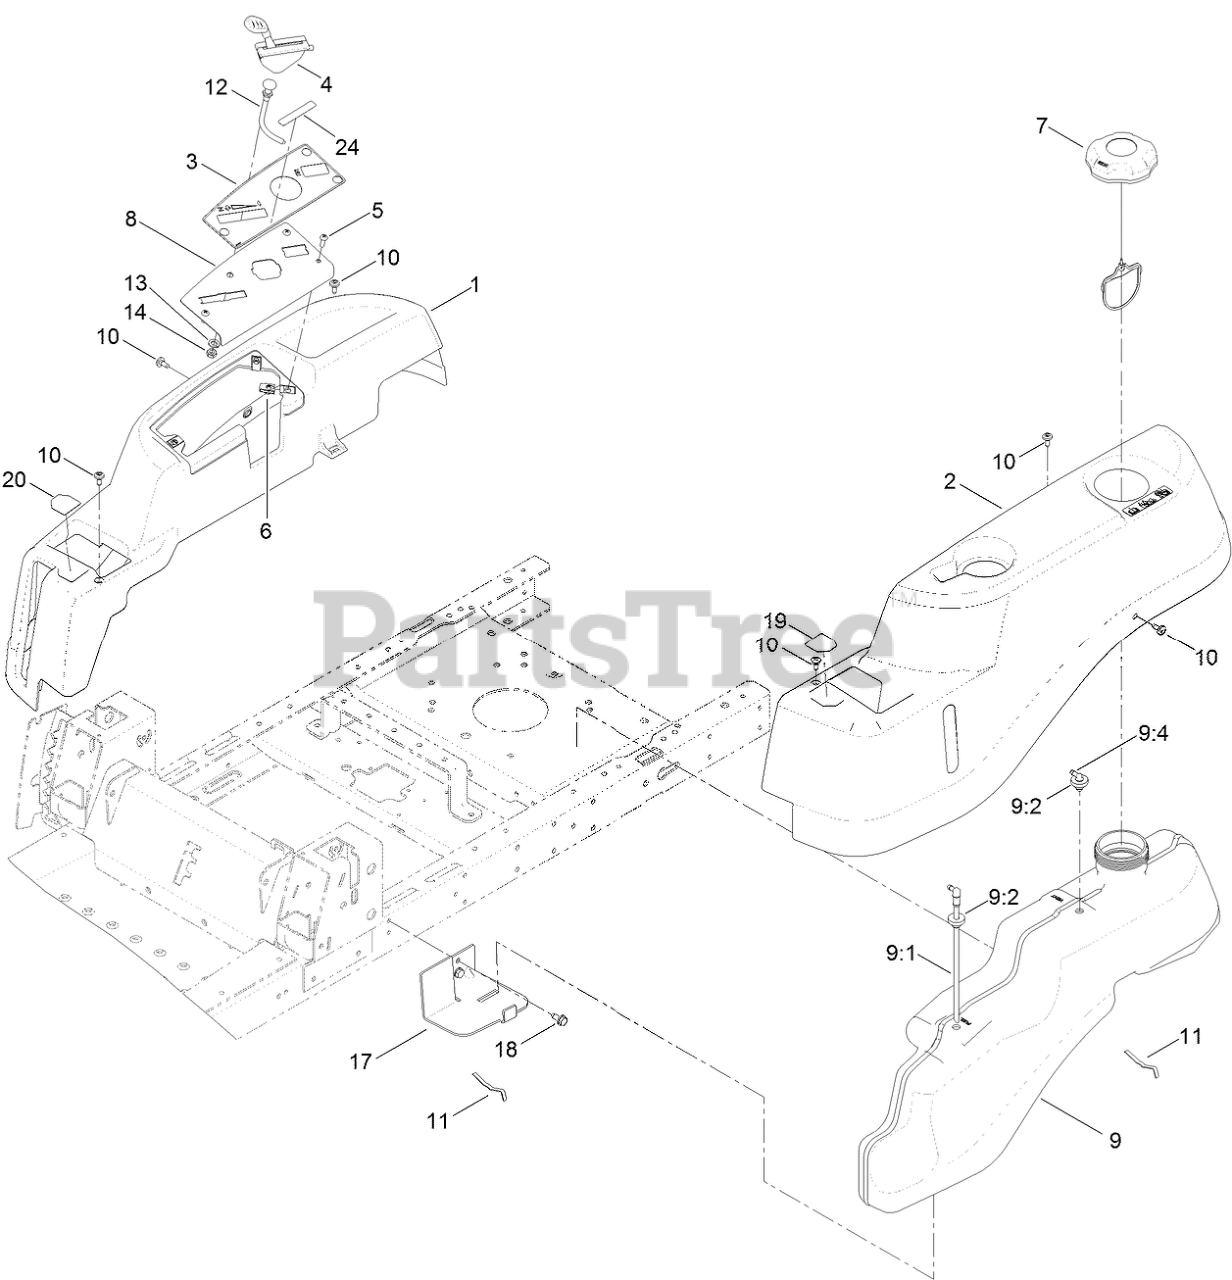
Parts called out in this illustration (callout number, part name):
1	POD-RH
2	POD-LH
3	DECAL-PANEL, CONTROL
4	CABLE-THROTTLE
5	SCREW-PRH
7	CAP-FUEL, RATCHETING
8	PLATE-CONTROL
9	FUEL TANK ASM
9:1	CONNECTOR-ELBOW, 90 DEG
9:2	BUSHING
9:4	FITTING-PLASTIC
10	SCREW-SHOULDER
11	SPRING
12	CABLE-CHOKE
13	WASHER-LOCK
14	NUT-HJ
17	SUPPORT-TANK, FRONT
18	SCREW-HWHTF
19	DECAL-CONTROL LEVER, LH
20	DECAL-CONTROL LEVER, RH
24	DECAL-SHUTDOWN
